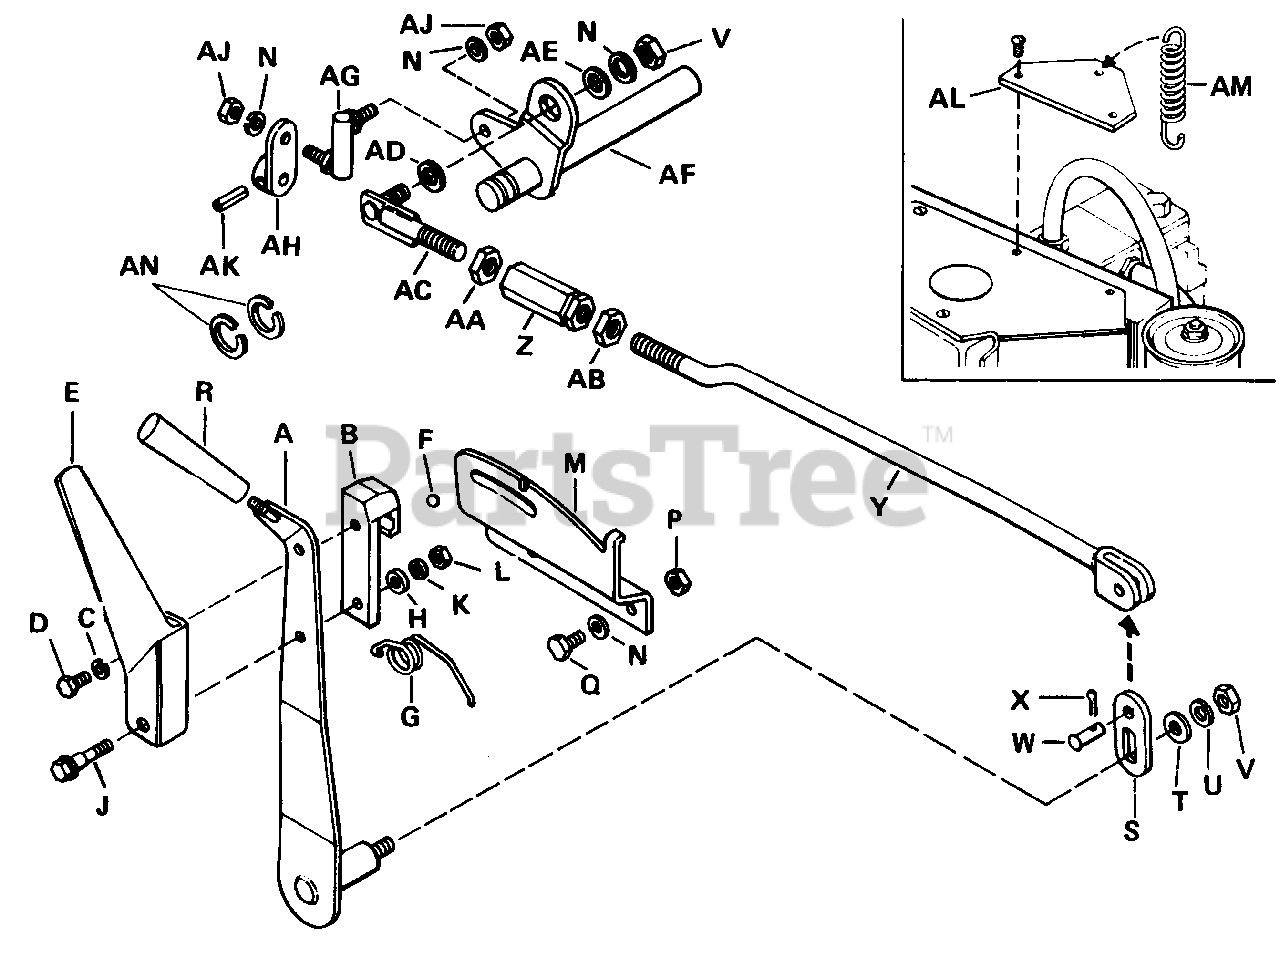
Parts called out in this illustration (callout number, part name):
A	Lever Assembly
B	Stop Clamp
C	Lock Washer, 1/4" Std.
D	Hex Capscrew, 1/4"-20 N.C. x 1/2"
F	Shift Ball Handle, 5/16"
J	Shoulder Bolt
K	Plain Washer, 1/4"
L	Full Hex Lock Nut, 1/4"-20
M	Support Plate
N	Lock Washer, 5/16"
P	Full Hex Nut, 5/16"-18
Q	Hex Capscrew, 5/16"-18 N.C. x 5/8"
T	Plain Washer, 3/8"
U	Lock Washer, 3/8"
V	Full Hex Nut, 3/8"-16
X	Cotter Pin, 3/32" x 3/4"
Y	Rod Assy., Control, Front
Z	Turn Buckle
AA	Full Hex Nut, 7/16"-14 L.H.
AB	Full Hex Nut, 7/16"-14 R.H.
AC	Rod Assy., Rear Control
AE	Plain Washer, 5/16"
AF	Shaft Assy., Control
AG	Ball Joint, Double End
AH	Link Assy., Control
AJ	Full Hex Nut, 5/16"-24
AK	Roll Pin, 1/4" x 1-1/4"
AL	Spring Clip
AN	Retaining Ring
